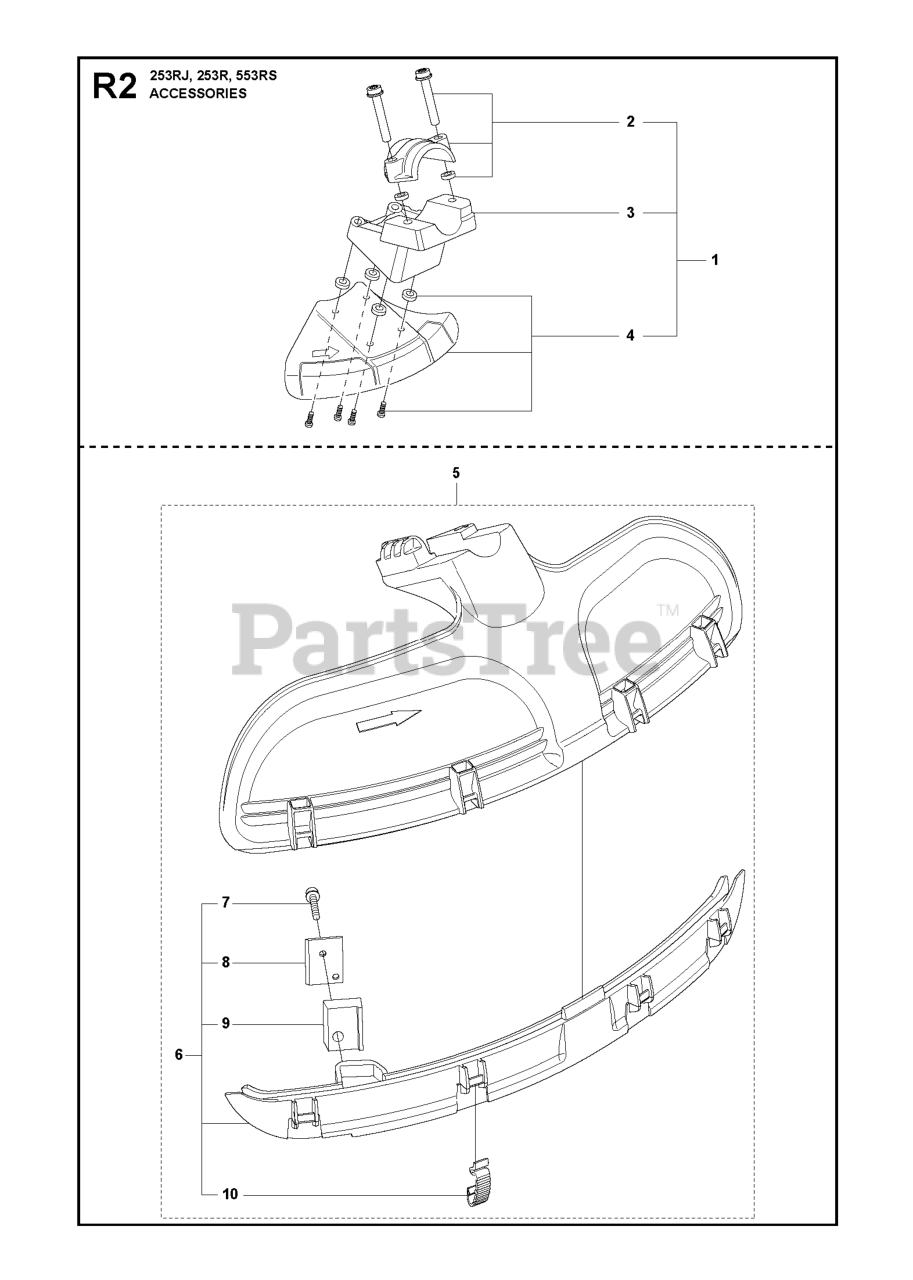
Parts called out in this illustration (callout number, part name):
5	COMBI PROTECTOR
6	SPLASH GUARD
8	LINE CUTTER
9	DISTANSBLOCK
